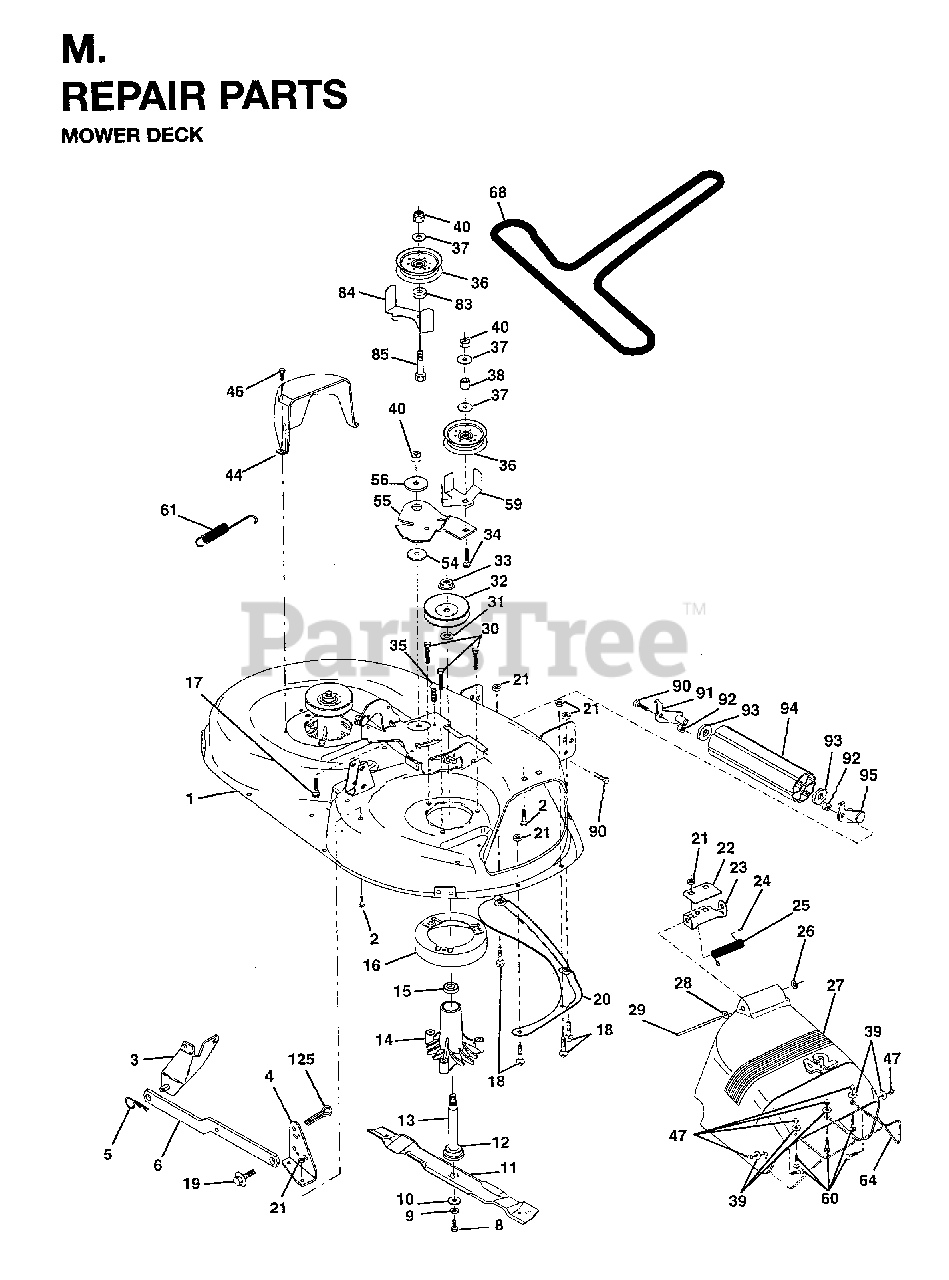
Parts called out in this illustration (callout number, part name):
1	DECK 42"
2	BOLT
3	BRKT ASM SWAY BAR
4	BRKT DECK SW BAR
5	RETAINER SPRING
6	REAR SUSP ARM
8	BLADE BOLT
9	WASHER, LOCK 3/8
10	WASHER.BLADE
11	BLADE 42"
12	BEARING
13	SHAFT ASM VENT
14	HSG MANDREL
16	STRIPPER
17	BOLT CARRIAGE
18	BOLT
19	BOLT SHD 5/16-18
20	BAFFLE
21	LOCKNUT
22	STIFFENER BRACKET
23	DEFLECTOR BRACKET
24	CAP-SLEEVE LT
25	SPRING TORSION
26	NUT PUSH M
28	WASHER - 15X7.3X1.6
29	ROD.HINGE
30	SCREW
31	WASHER
32	MANDREL PULLEY
33	NUT
35	FASTENER.XMAS.TREE
36	FLAT IDLER PULLEY
37	WASHER
38	IDLER SPRING SPACER
39	WASHER
40	LOCKNUT
44	GUARD MANDREL LH BLACK
46	SCREW.1/4-20X5/8
47	NUT
54	HARDENED WASHER
55	IDLER ARM
56	SPACER RETAINER
59	GUARD, BELT
60	SCREW.10-24X5/8
61	SPRING EXTENSION
68	V-BELT TRIPATH
84	KEEPER BELT
85	BOLT
91	BRACKET LH (A)
92	LOCKNUT
94	NOSE ROLLER
95	BRACKET RH (B)
125	COTTER PIN
